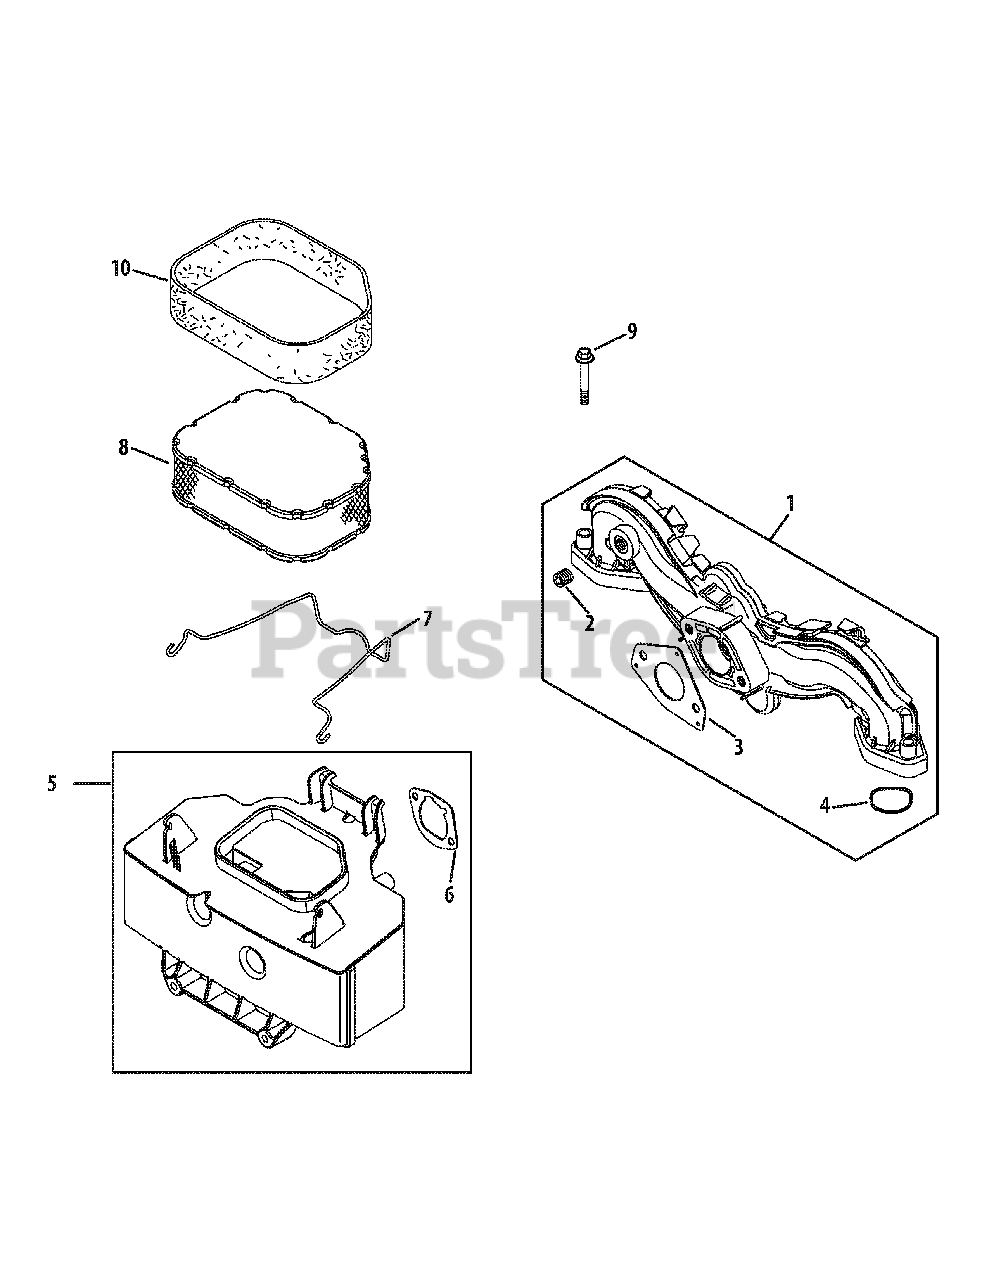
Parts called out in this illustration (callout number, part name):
1	Intake Manifold Kit (Inc. 2-4)
3	Gasket, Carburetor
5	Air Cleaner Base Kit (Inc. 5 & 6)
6	Air Cleaner Base Gasket
7	Air Cleaner Element Latch
8	Air Filter Element with Pre-Cleaner
9	Flg. Screw, M6 X 1.0 X 40
10	Pre-Cleaner Element
